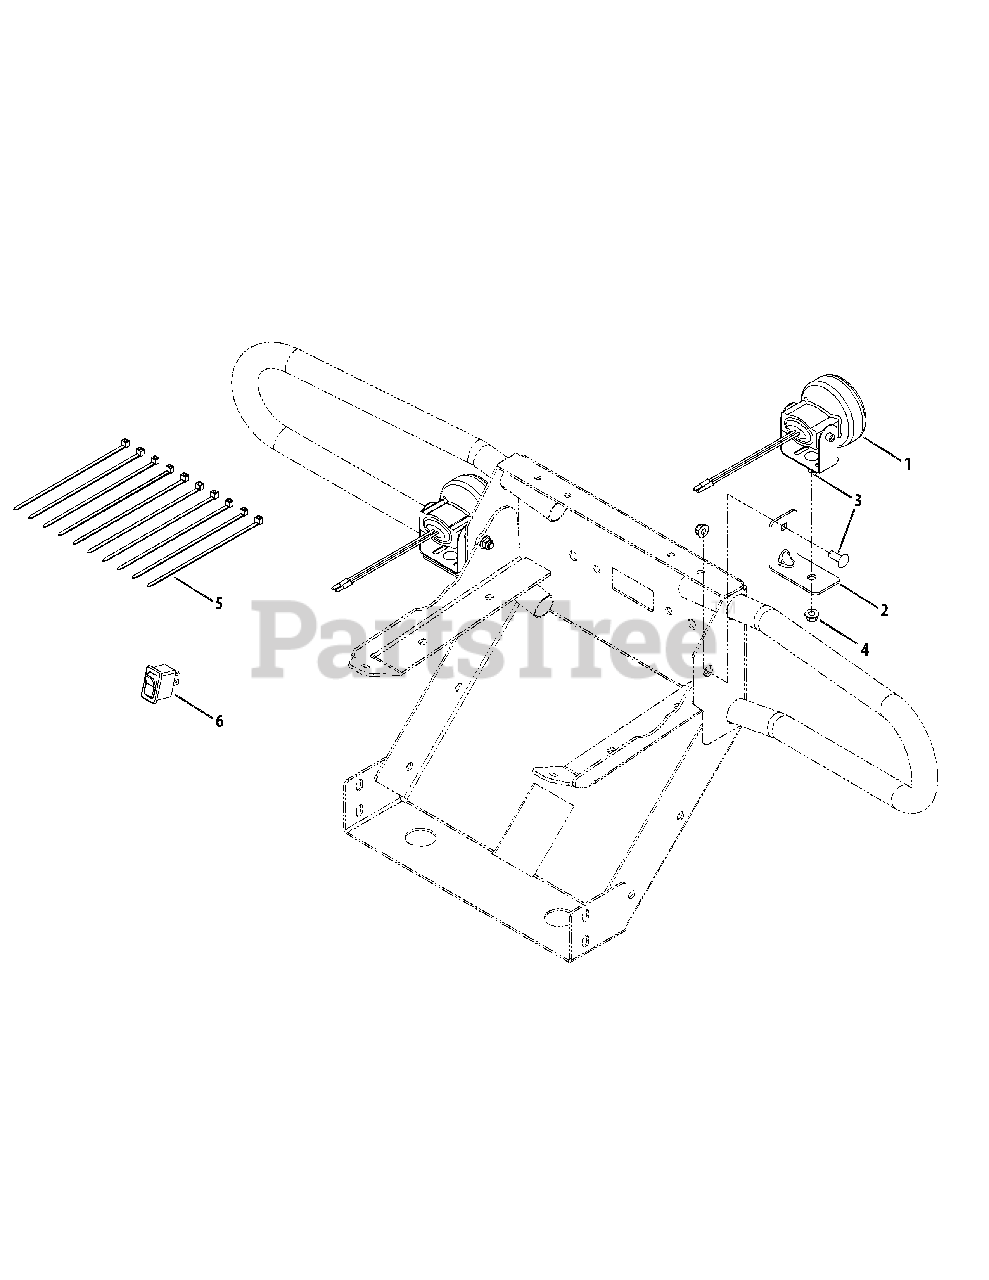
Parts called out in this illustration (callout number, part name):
1	Term, Bullet Molex
2	Fog Light Bracket
3	Carriage Bolt, 5/16-18 x .875
4	Flange Lock Nut, 5/16-18
5	Cable Tie
6	Headlight Rocker Switch
